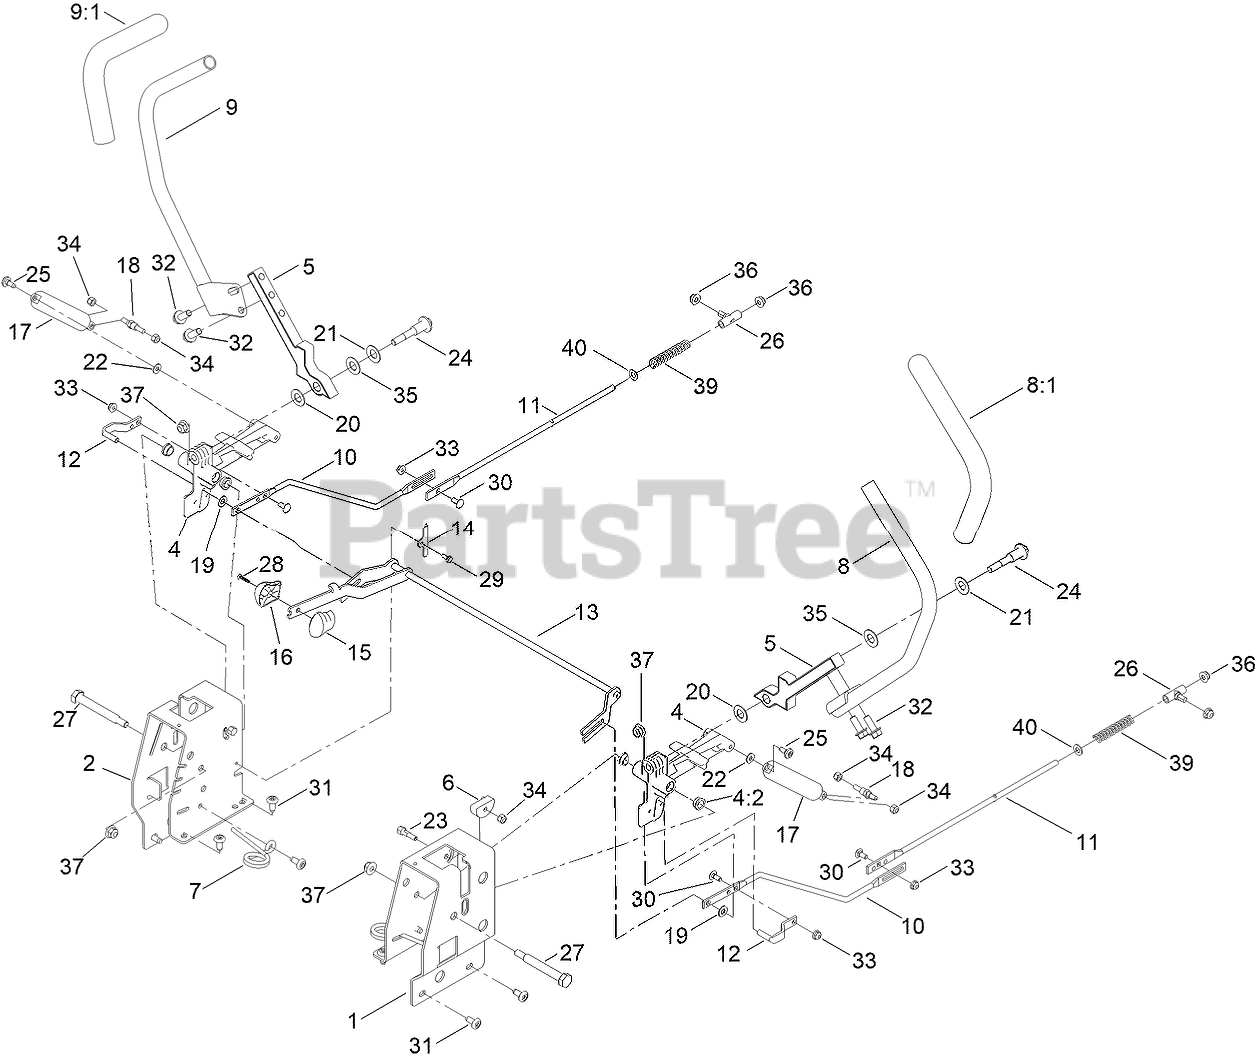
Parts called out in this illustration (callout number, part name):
1	PLATE-CONTROL BOX, LH
2	PLATE-CONTROL BOX, RH
4	ACTUATOR ARM ASM
4:2	BUSHING-FLANGE
5	ARM-CONTROL
6	ECCENTRIC
7	SPRING-TORSION
8	HANDLE-CONTROL, LH
9	HANDLE-CONTROL, RH
10	ROD-HYDRO, FRONT
11	ROD-HYDRO, REAR
12	PIN-ROD, HYDRO
13	SPEED CONTROL ASM
14	PLATE-RETAINER
15	KNOB-RH
16	KNOB-LH
17	DAMPER-NON CAVITATING
18	STUD-DAMPER
19	SPACER-NYLON
20	WASHER-NYLON
21	WASHER-BELLEVILLE
22	WASHER
23	BOLT-PIVOT, ECCENTRIC
24	BOLT-PIVOT
25	SCREW-SHOULDER
26	MOUNT-ROD, HYDRO
27	BOLT-PIVOT
28	SCREW-PPH
29	SCREW-TAPTITE
30	SCREW-CARR
32	SCREW-HHF
33	NUT-HF
34	NUT-LOCK, NI
35	WASHER
36	NUT-HF
37	NUT-HF, NI
39	SPRING-COMPRESSION
40	WASHER-PLAIN
